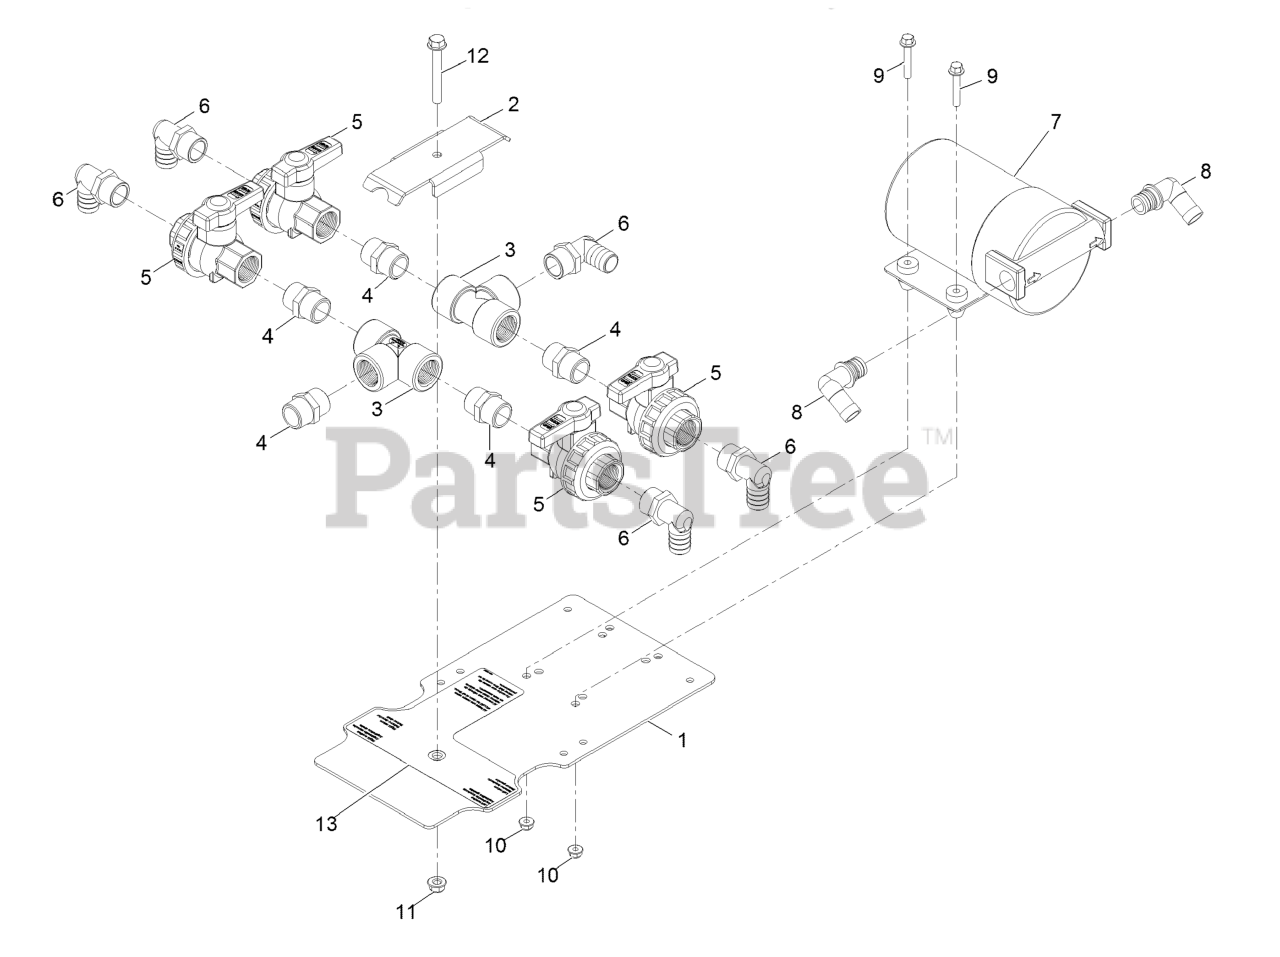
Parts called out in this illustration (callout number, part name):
1	MOUNT-PLATE, LIQUID VALVE
2	PLATE-CLAMP, LIQUID VALVE
3	FITTING-TEE
4	FITTING-NIPPLE
5	VALVE-UNION, 3/4
6	FITTING-ELBOW, 90
7	7.0 REMCO PUMP
8	FITTING-ELBOW, 3/4QD X 3/
9	Screw-HHF
10	Nut-Hex Flange
11	Nut-Hex Flange
12	Screw-HHF
13	DECAL-VALVE, TANK
